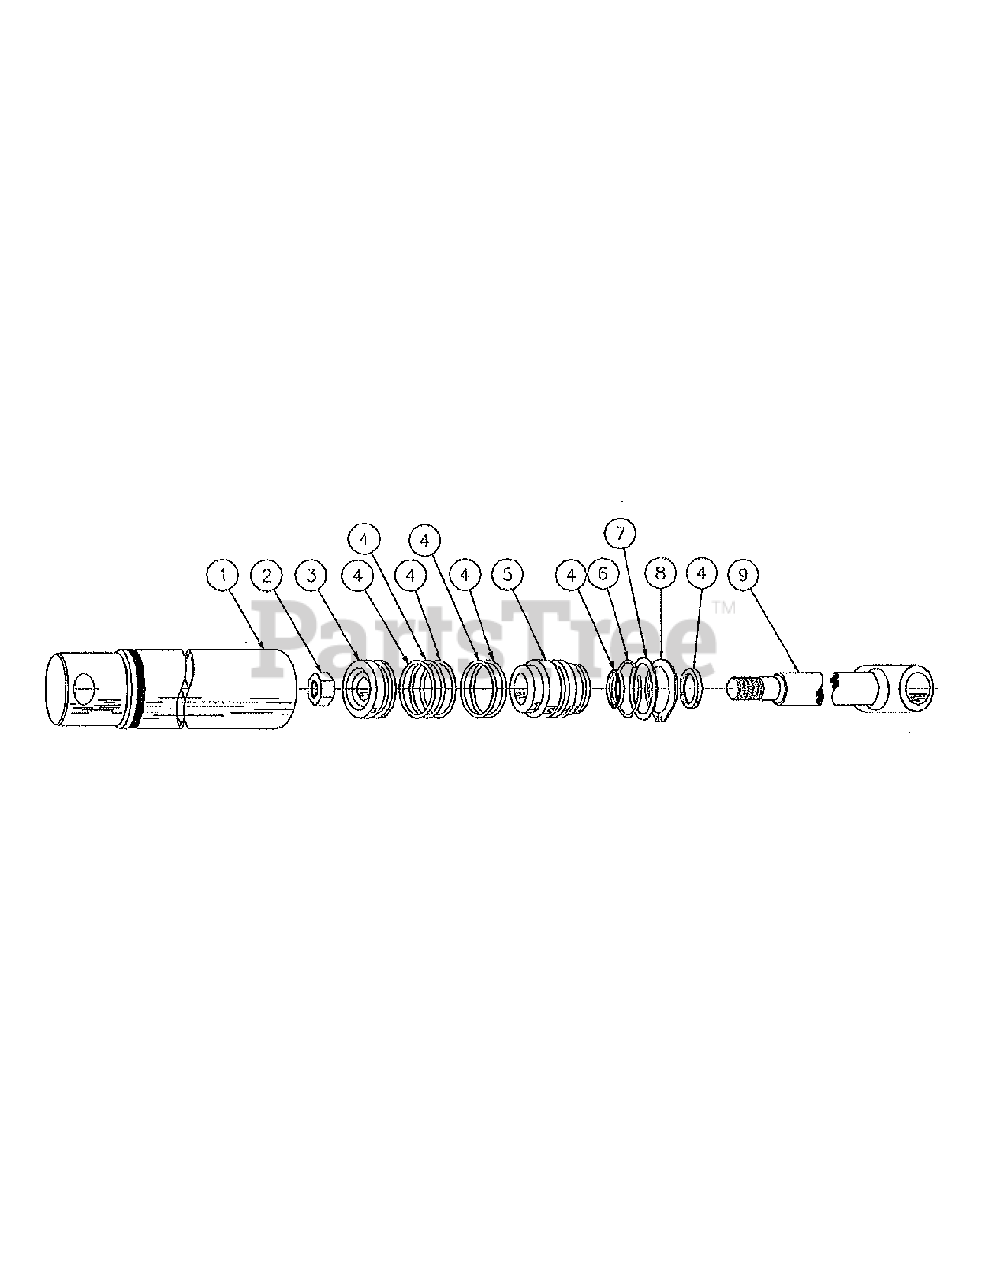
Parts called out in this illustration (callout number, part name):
1	Tube Assembly
6	Retaining Ring
8	Retaining Ring
9	Rod Assembly
